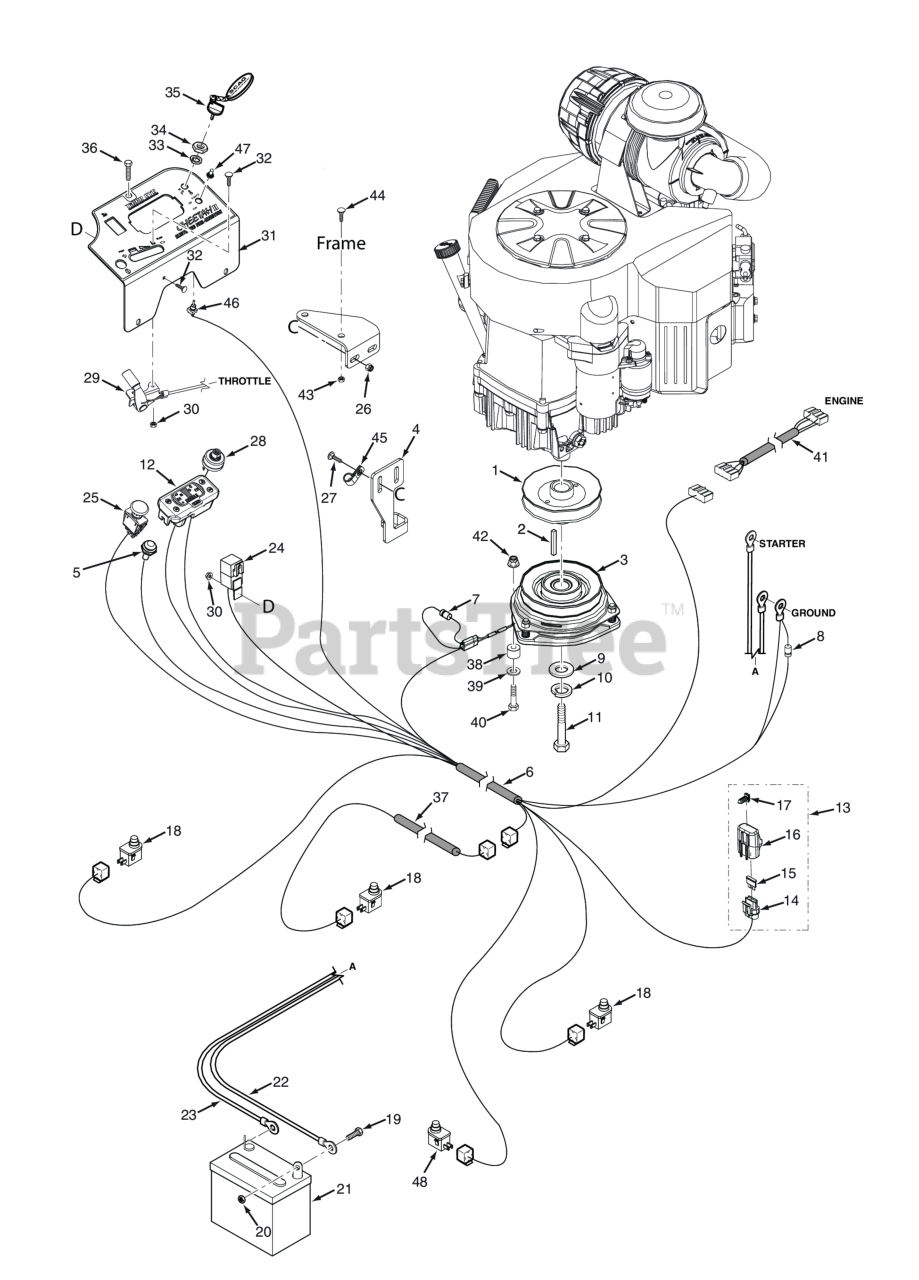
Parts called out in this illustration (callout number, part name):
1	Pulley, 5.80" Dia. - 1.125 Bore
2	Key, 1/4 x 1/4 x 3-1/4�
3	Electric Clutch w/Tag - GT-5 (ECV860, ECV940)
4	Bracket, Anti-Rotation
5	Indicator Light, Glow Plugs (Includes Mounting Hardware)
6	Wire Harness, SCZII-EFI
7	Diode, 600V 6 Amp
8	Decal, Forward Speed Selector
9	Flatwasher, 7/16-.469 x 1.75 x .25 (48, 52)
10	Lockwasher, 7/16� Spring
11	Bolt, Hex Head 7/16-20 x 2-1/4" w/Patch (Kawasaki)
12	Tiger Eye, Cluster Gauge
13	Single Fuse Assy., Excluding Fuse
14	Fuse Holder Assembly
15	FUSE, 20 AMP BLADE TYPE AUTOMOTIVE
16	Cover, Sealed Single
17	Clip, Fuse Holder
18	Switch, Interlock, Normally Open
19	Bolt, Hex Head 1/4-20 x .5" Battery, (Not Available Through Scag)
20	Nut, 1/4 - 20 Hex
21	Battery
22	Battery Cable, 18" Black (Kohler)
23	Battery Cable, 25" Red
24	Switch, PTO - 10 Amp
25	Nut, Flange Head Elastic Stop 5/16-18
26	Bolt, Carriage 5/16-18x1" (large frame units only)
27	KEY SWITCH(INCLUDES MOUNTING HARDWARE)
28	Control Cable (Kawasaki FX921 Throttle & Choke Cable)
29	Control, E-Gov Throttle
30	Nut, Elastic Stop #10-24
31	Instrument Panel w/Decal
32	Bolt, Carriage #10-24 x 1/2"
33	LOCK WASHER, 5/8" INTERNAL TOOTH
34	Nut, 5/8-32 Special
35	Key, Assembly w/Fob
36	CAP SCREW, 1/4-20 X 1/2" SERRATED FLANGE HEX
37	Wire Harness, Operator Platform -SCZ
38	Bushing, UHMW
39	Flatwasher, 5/16-.375 x .875 x .083 (35BV & 37BV-EFI)
40	Bolt, Hex Head 5/16-18 x 1-1/2" (Right Front Engine Mounting, Briggs and Kohler Only)
41	Wire Harness Adapter, Briggs & Stratton 37 BV-EFI
42	HEX NUT, ELASTIC STOP LOCK, 5/16-18
43	NUT, 3/8-16 SERRATED FLANGE HEX HEAD
44	Carriage Bolt, 3/8-16 x 1.0"
45	Clamp, Cable 1/2" I.D.
46	SWITCH, ON / OFF
47	BOOT, SWITCH
48	Switch, N/C
